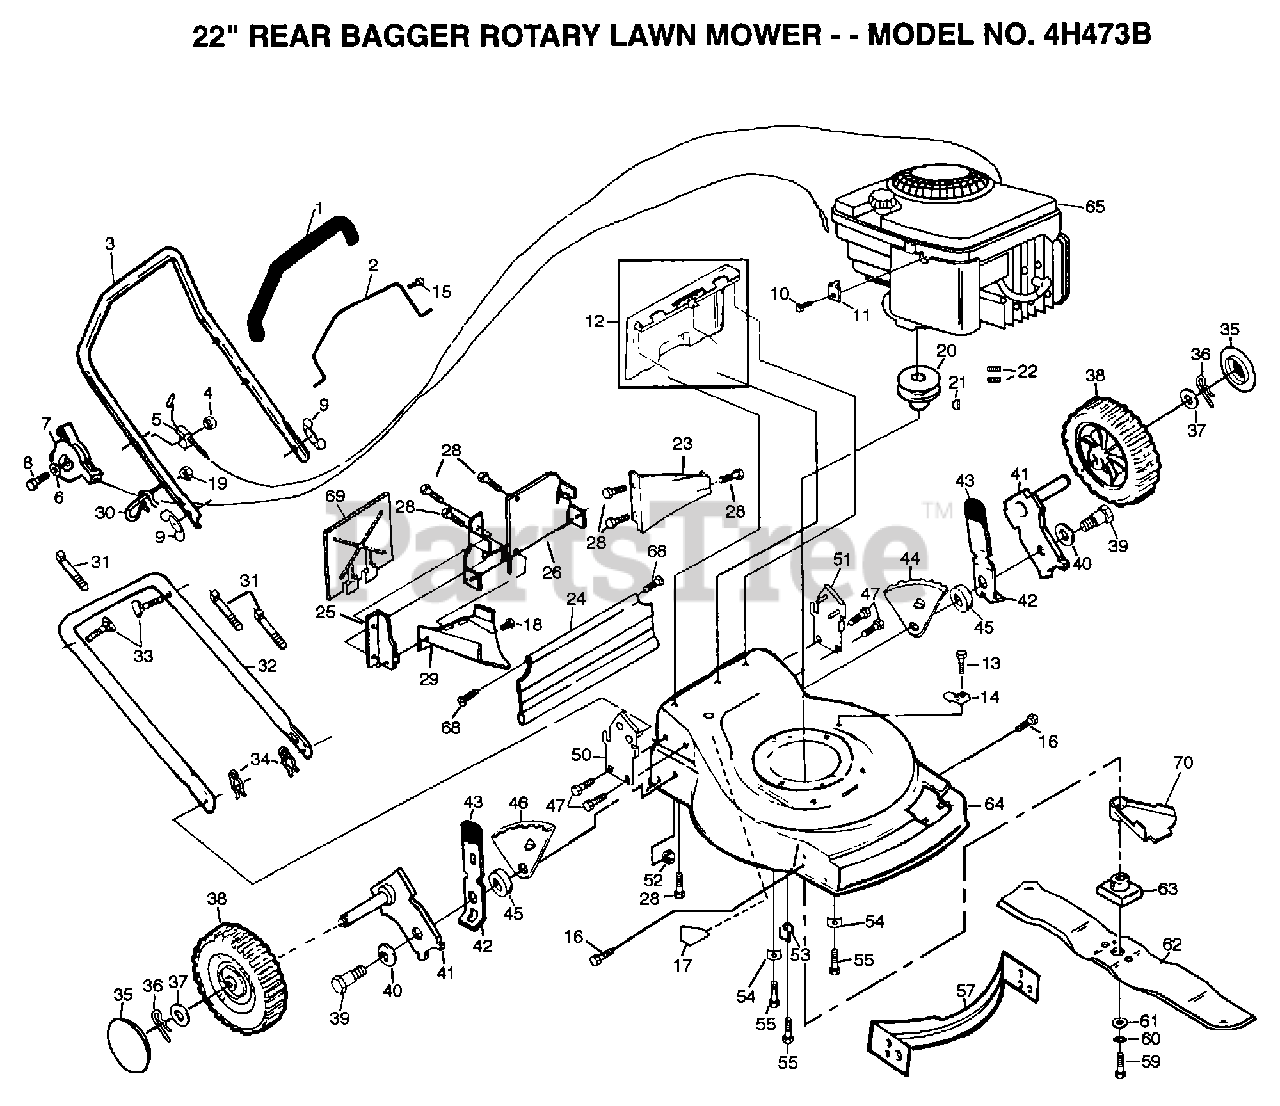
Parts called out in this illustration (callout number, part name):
2	"BAR,CONT"
5	"CABLE,ENG ZONE CO"
6	WASHER PM
7	"CONTROL, THROTTLE"
9	"NUT,WING PM"
10	SCREW PM
11	CABLE CLAMP
13	TAPPING SCREW
14	GUIDE CLIP PM
15	"SCREW,PAN HD"
16	SCREW
17	DECAL HYT
18	SCREW PM
19	NUT
20	ENGINE.PULLEY.FWG
21	HI PRO KEY PM
22	SCREW
23	REAR BAFFLE
26	PLATE.BACK
28	SCREW
29	DISCHARGE BAFFLE
30	ROPE GUIDE
33	BOLT.HANDLE.LM
34	HAIRPIN COTTER
35	HUB CAP
36	RETAINER CLIP PM
37	WASHER
40	"WASHER, BELLEVIL."
41	AXLE ARM
42	SPRING SELECTOR
43	KNOB PM
47	SCREW
52	LOCKNUT PM
53	DEBRIS SHLD RET
55	SCREW
59	SCREW
60	LOCKWASHER
61	"WASHER,HARDEN"
63	ADAPTOR.BLADE.LM
64	KIT.HSG.22RD.FWGD
68	HINGE SCREW
69	MULCHER PLATE
